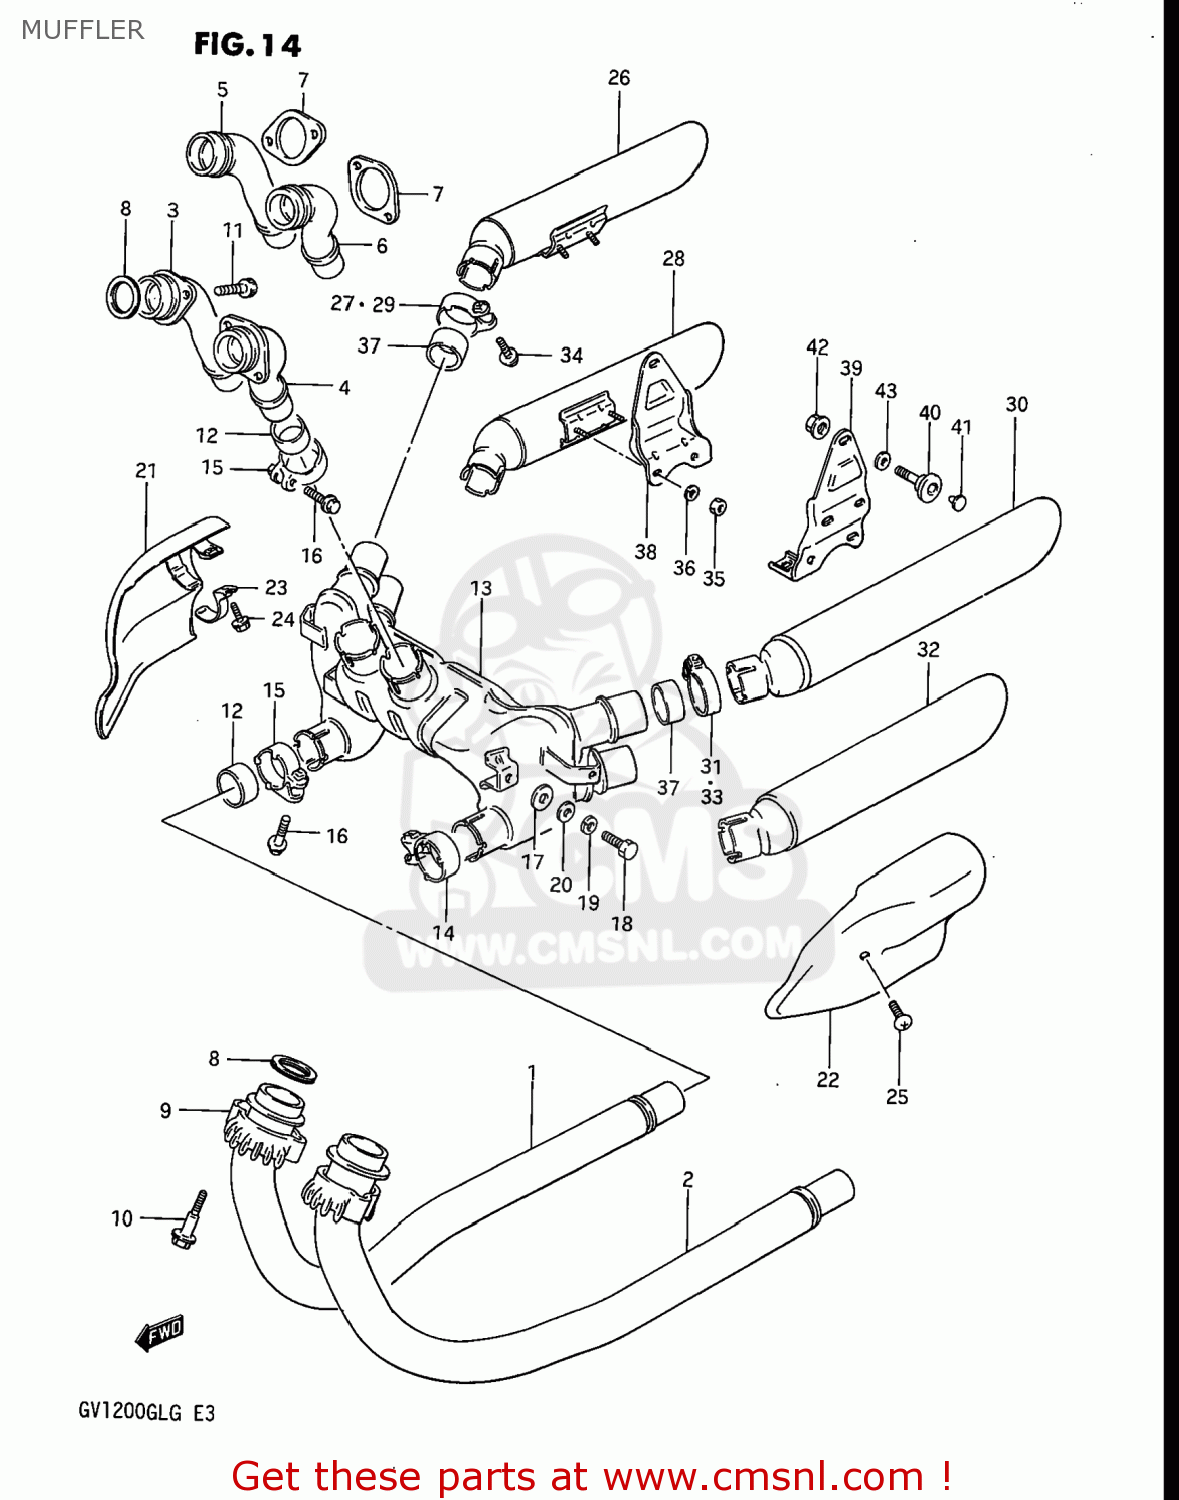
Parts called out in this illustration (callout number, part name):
1	PIPE,EXHAUST,FRONT,RIGHT
2	PIPE,EXHAUST,FRONT,LEFT
3	FLANGE,EXHAUST PIPE
4	COVER,EXHAUST PIPE
5	FLANGE,EXHAUST PIPE
6	COVER,EXHAUST PIPE
7	FLANGE,EXHAUST PIPE,REAR
8	GASKET,EXHAUST PIPE (NAS)
9	CLAMP(H:21)
10	BOLT
11	BOLT, REAR
12	CONNECTOR,MUFFLER
13	BODY,PRE MUFFLER
14	CLAMP,PRE MUFFLER RH
15	CLAMP,PRE MUFFLER LH
16	BOLT
17	GASKET
18	BOLT
19	WASHER,LOCK,8.
20	WASHER
21	COVER,PRE MUFFLER,RIGHT
22	COVER,PRE MUFFLER
23	CLAMP,MUFFLER COVER
24	BOLT
25	SCREW 6X12
26	BODY,MUFFLER
27	CLAMP,MUFFLER CONNECTOR
28	BODY,MUFFLER
29	CLAMP,MUFFLER CONNECTOR
30	BODY,MUFFLER
31	CLAMP,MUFFLER CONNECTOR LH
32	BODY,MUFFLER
33	CLAMP,MUFFLER CONNECTOR LH
34	BOLT
35	NUT
36	LOCK WASHER
37	CONNECTOR,MUFFLER
38	BRACKET,MUFFLER,RIGHT
39	BRACKET,MUFFLER,LEFT
40	BOLT
41	CAP
42	NUT
43	WASHER(10.5X20X3.2)
